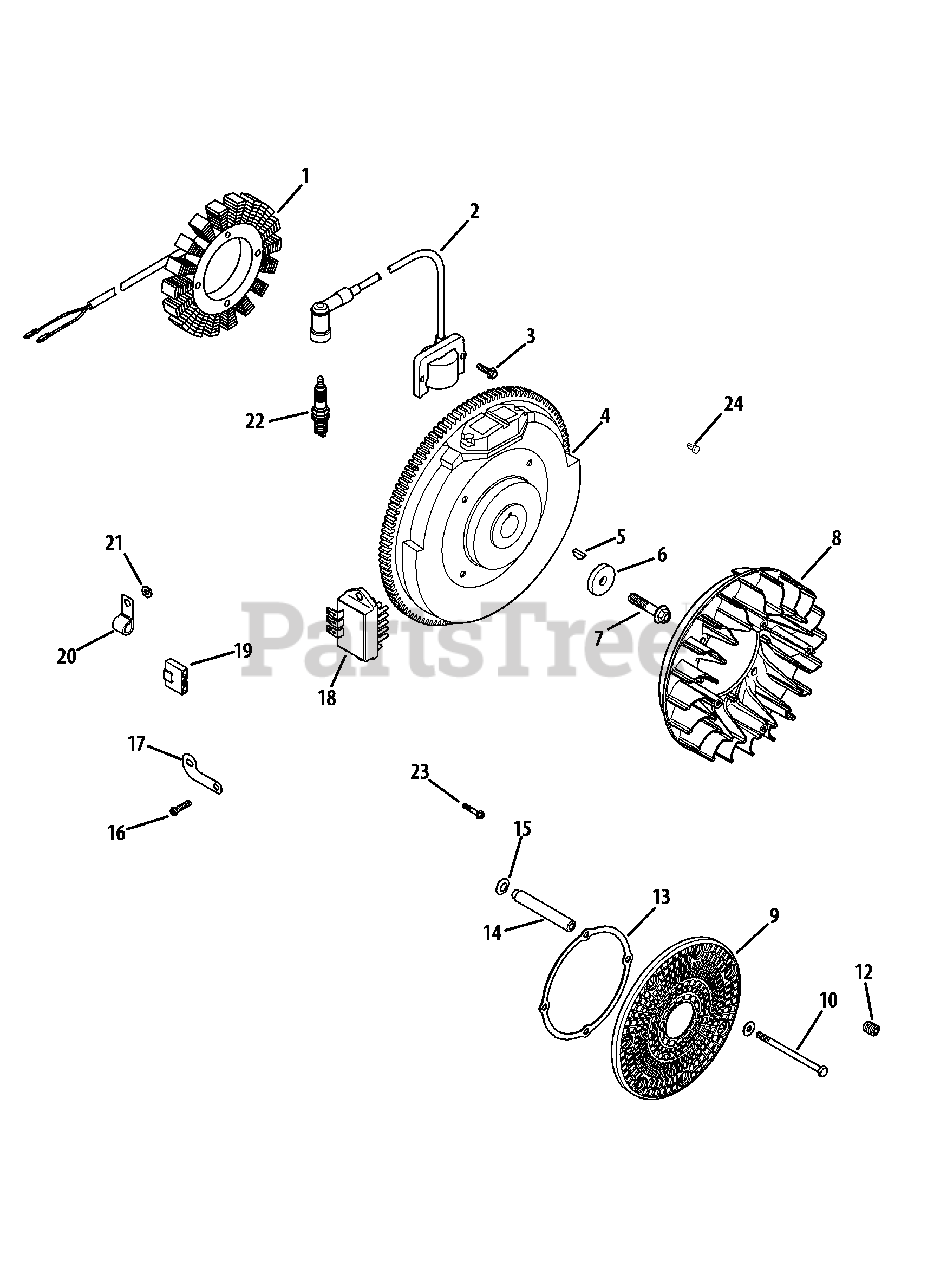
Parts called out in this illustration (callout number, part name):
1	25 Amp Stator Assembly Kit
2	Module Ignition Kit (CDI Fixed)
3	Thread Forming Screw
5	Key, 3/16 x 5/8
6	Flat Washer, 13/32
7	Flange Screw, M10 x 1.5 x 45
8	Fan
10	Cap Screw, M6 x 1.0 x 99.5
11	Flat Washer, 1/4 x 5/8
12	Socket Set Screw, #10-24 x 1/4
13	Support Ring
15	Spring Washer, 10 MM
16	Hex Flange Hi-Lo Screw
17	Ground Strap Bracket
18	Rectifier Regulator
20	Cable Clip
21	Flat Washer, 1/4 x 1/2
22	Spark Plug (Std.)
23	Flange Screw, M8 x 1.25 x 45
24	Washer Head Tap Screw, #8-18 X 1/2
